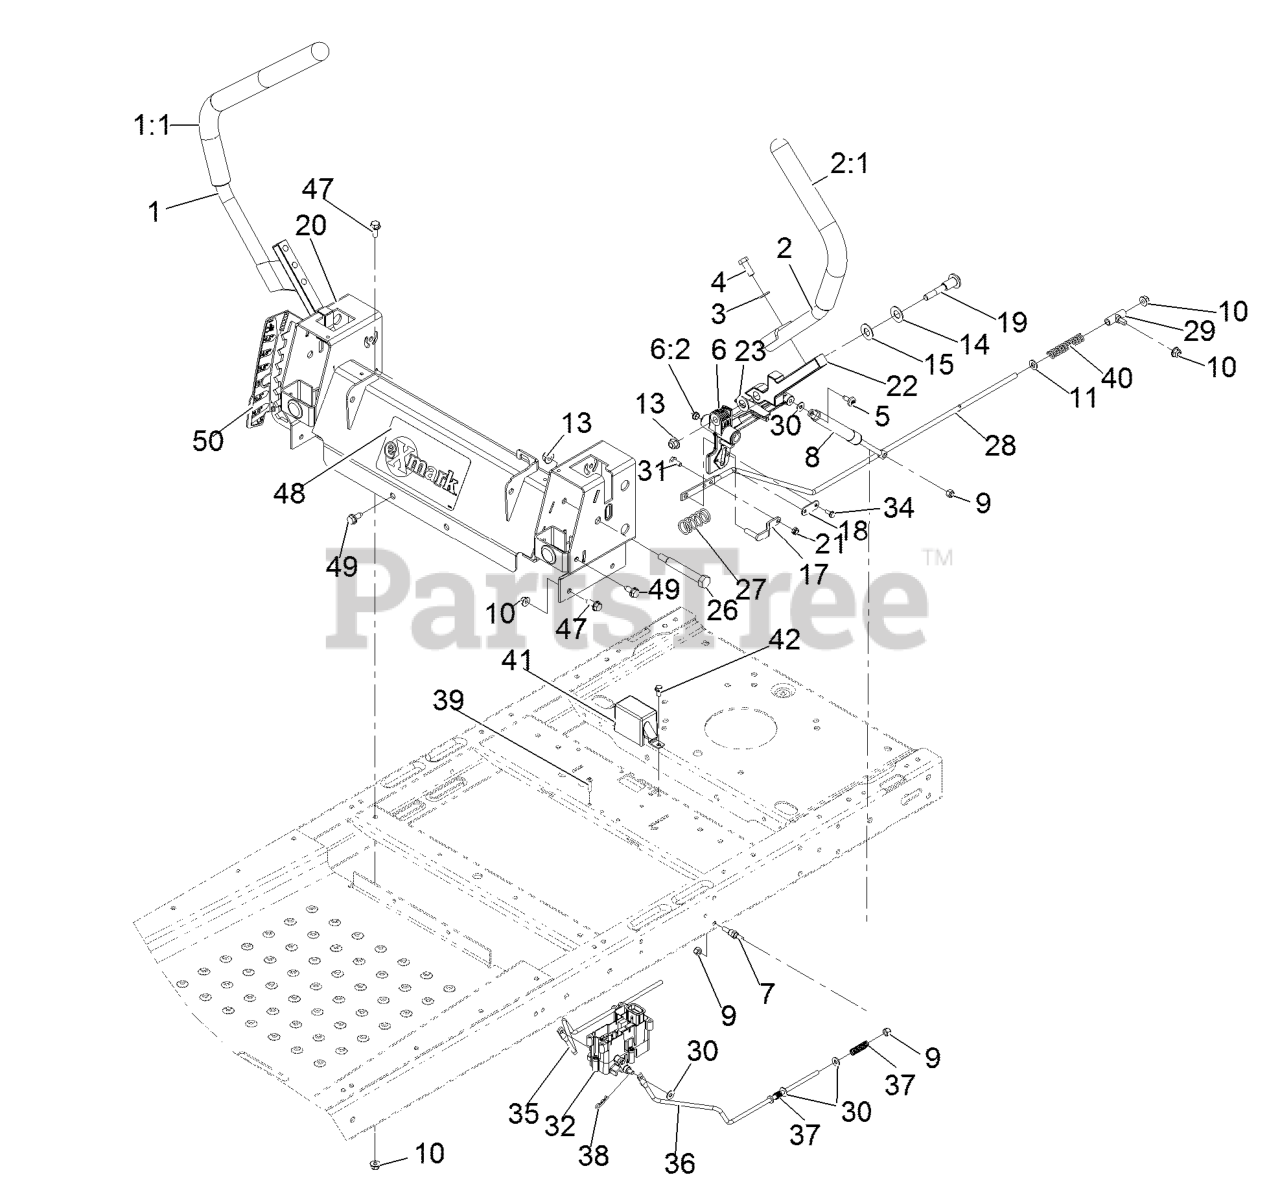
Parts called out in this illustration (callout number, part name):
1	HANDLE-CONTROL, RH
2	HANDLE-CONTROL, LH
3	WASHER-FLAT
4	SCREW-HH
5	SCREW-SHOULDER
6	ACTUATOR ARM ASM
6:2	BUSHING-FLANGE
7	STUD-DAMPER
9	NUT-LOCK, NI
10	NUT-HF, NI
11	WASHER-PLAIN
13	NUT-HF, NI
14	WASHER-BELLEVILLE
18	PLATE-STOP, HYDRO
19	BOLT-PIVOT
20	CONTROL BOX ASM
21	NUT-LOCK, NI
23	WASHER-NYLON
26	BOLT-PIVOT
27	SPRING-RETURN
28	ROD-HYDRO
29	MOUNT-ROD, HYDRO
31	SCREW-HH
34	SCREW-TAPTITE
35	ROD-BRAKE, WIDE (RH)
36	ROD-BRAKE, WIDE (LH)
37	SPRING-COMPRESSION
39	SCREW-PPH
40	SPRING-RETURN, NEUTRAL
41	COVER-BRAKE
42	SCREW-HWH
47	SCREW-HHF
49	Screw-HWH 5/16-18 X 3/4 Tf
50	DECAL-HOC
